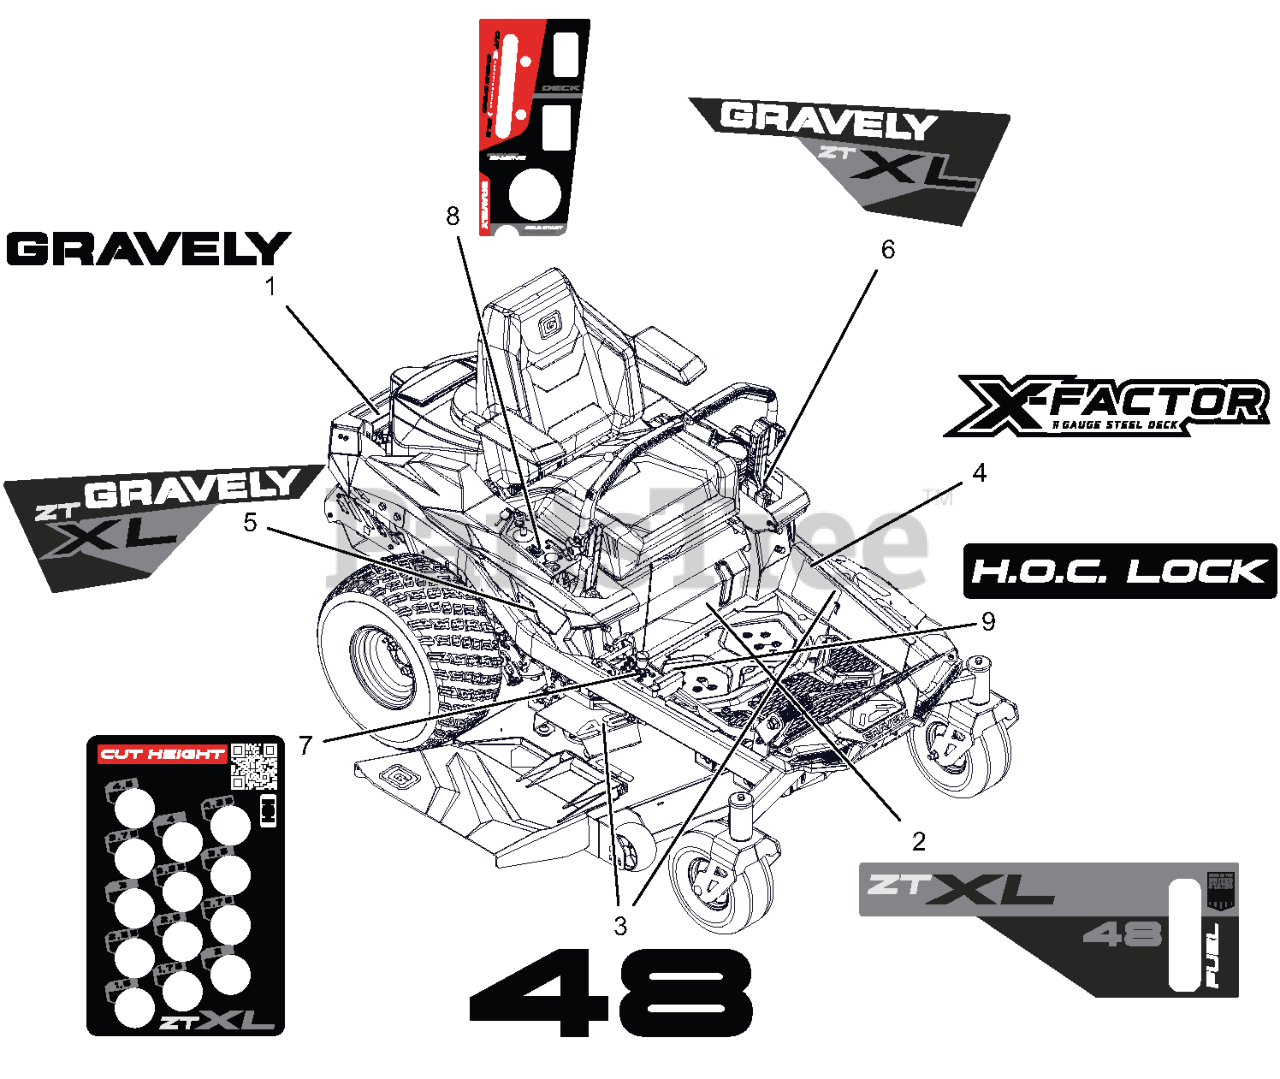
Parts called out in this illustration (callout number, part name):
1	DECAL- GRAVELY
2	DECAL- ZTXL 48-KICK PLATE
3	DECAL- DECK 48"
4	DECAL- DECK X-FACTOR
5	DECAL- ZT XL FENDER RH
6	DECAL- ZT XL FENDER LH
7	DECAL- HEIGHT OF CUT-XL
8	DECAL- CONTROL PANEL-GRAVELY
9	DECAL- HOC LOCK
